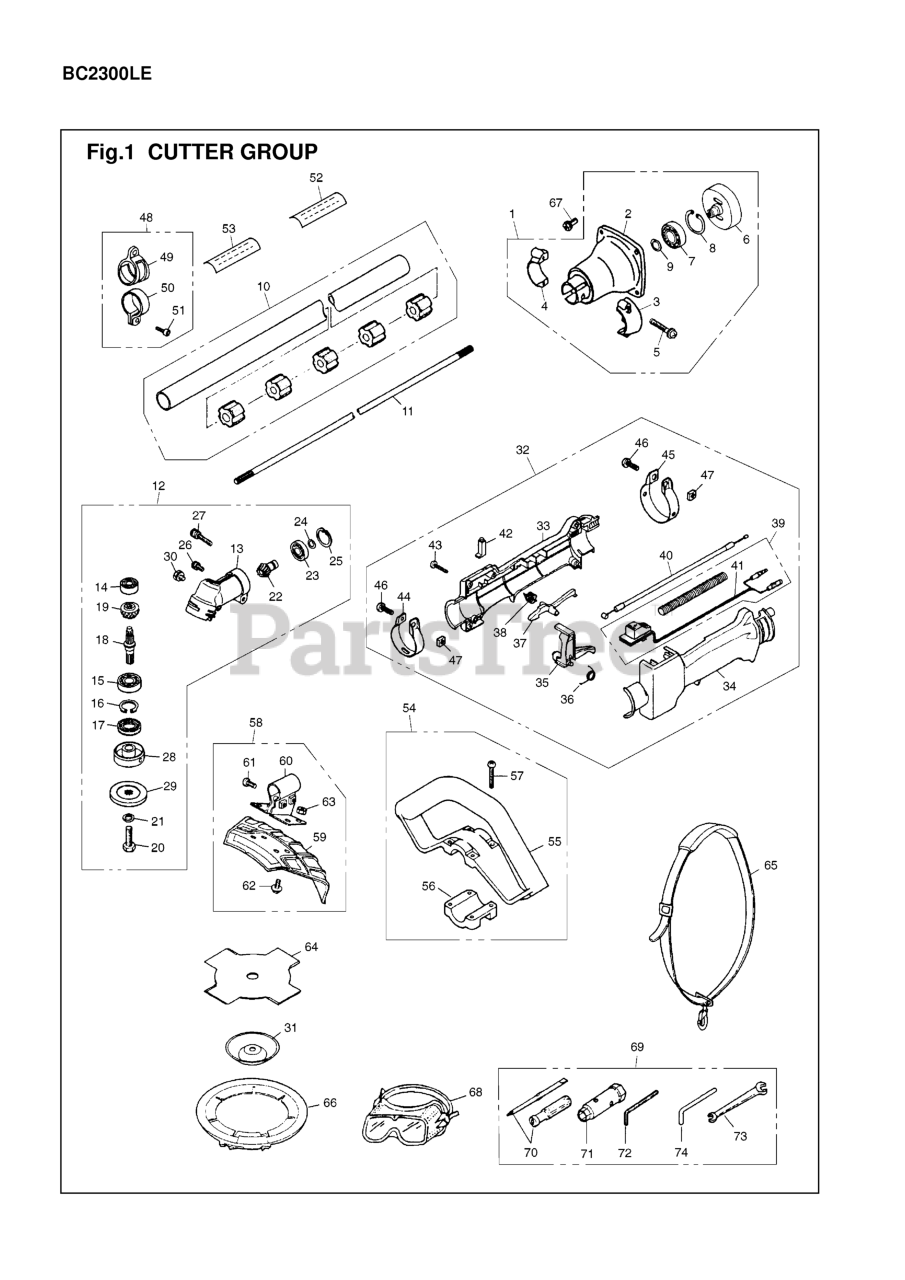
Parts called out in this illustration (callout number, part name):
1	HOUSING ASSY
3	CLAMP, LEFT
4	CLAMP, RIGHT
5	BOLT
7	BEARING
8	RING
9	RING
10	PIPE (USE -11302)
11	SHAFT, DRIVE
12	GEARCASE ASSY
13	GEARCASE
14	BEARING
17	SEAL
18	SHAFT, GEAR
20	BOLT
21	WASHER
23	BEARING
24	SNAP RING
25	SNAP RING
26	BOLT
27	BOLT
28	HOLDER (A)
29	HOLDER (B)
31	COVER (RPLS 6460-13280)
32	GRIP ASSY
36	SPRING
38	SPRING
39	SWITCH COMP
40	CABLE COMP
41	CORD COMP
43	SCREW
45	BAND
47	NUT
48	HANGER ASSY
49	HANGER (REPLACES -18100)
52	PLATE NAME
53	PLATE, CAUTION
54	HANDLE ASSEMBLY
55	HANDLE
58	GUARD ASSY.
59	GUARD
65	STRAP ASSY
66	COVER (REPLACES D0041) ACC.
67	BOLT, M6 x 20
69	TOOL SET
70	DRIVER
73	SPANNER
74	BAR
